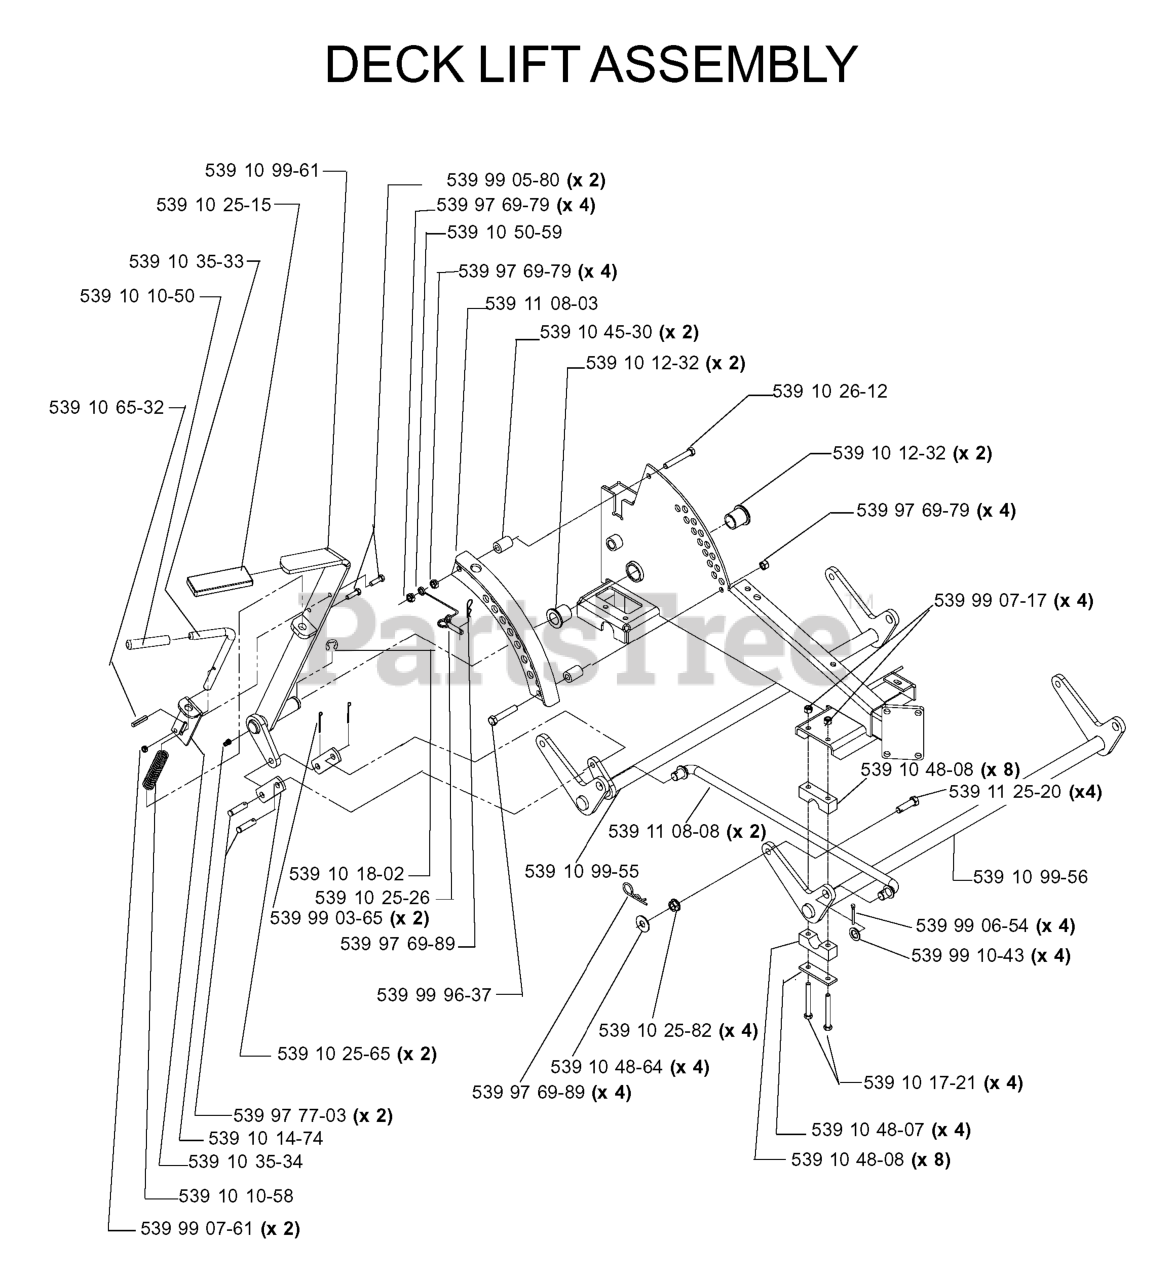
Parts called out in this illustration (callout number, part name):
1	SERVICE KIT OIL PUMP
3	CLUTCH DRUM ASSY
4	FRICTION DISC,CLUTCH 36/41
